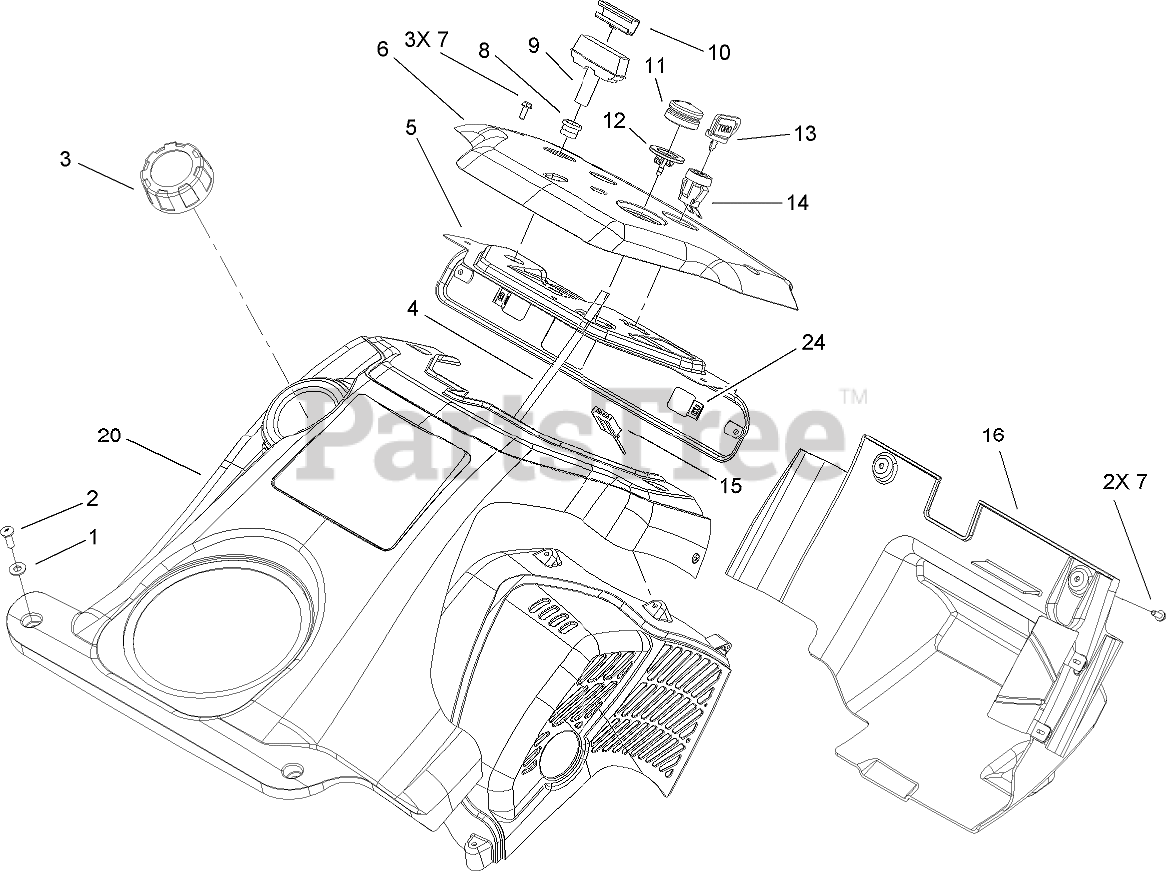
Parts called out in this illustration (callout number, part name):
1	WASHER-FLAT
2	SCREW-PPH
3	GAS CAP ASM
4	HOSE-PRIMER
5	PANEL-SUPPORT, CONTROL
6	PANEL-CONTROL
7	SCREW-HWH
8	GUIDE-ROPE, STARTER
9	HANDLE-START
10	CLIP-STARTER
11	BULB-PRIMER
12	BODY-PRIMER
13	KEY-IGNITION
14	SWITCH
15	CONNECTOR-BODY
16	LOWER SHROUD/BAFFLE ASM
20	UPPER SHROUD ASM
24	NUT-SPEED
